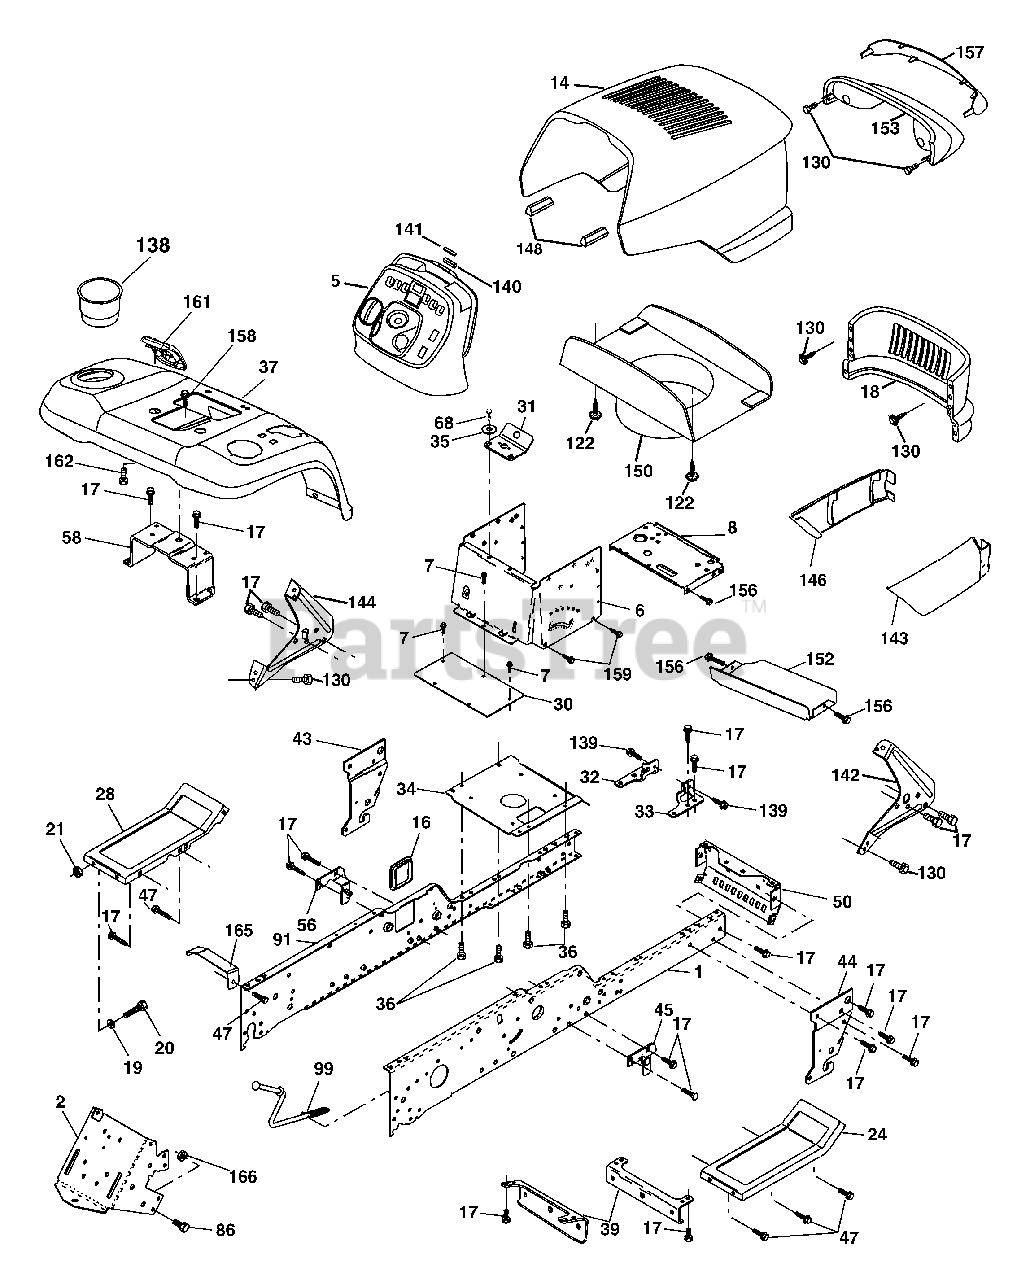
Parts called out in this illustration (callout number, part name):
1	Rail, Frame RH
2	Drawbar, Gt
5	Dash
6	Dash Asm., Lower
7	Screw, Thd Cut 1/4-20x 1/2
8	Support, Battery
14	Hood Asm., Pnt
16	Cover, Access
17	Screw, 3/8-16 x 3/4
18	Grille
19	Washer 13/32 x 13/16 x 12 Ga.
20	Bolt, Fin Hex 3/8-16 x 1
21	Nut, Lock Hex w/Ins. 3/8-16 Unc
24	Footrest, RH
28	Footrest, LH
30	Saddle, Hydro 1995
31	Bracket, Supt 1-pc VGT Steering
32	Bracket, Pivot Chassis LH
33	Bracket, Pivot Chassis RH
34	Plate Asm. Engine Chassis
35	Washer 11/32 x 11/16 x 16 Ga.
36	Screw 5/16-18 x 3/4
37	Fender, Pnt.
39	Bracket, Axle Front
43	Bracket, Spnsn Front Lh
44	Bracket, Spnsn Front Rh
45	Bracket Asm., Susp Chassis Rh
47	Screw Thdrol 3/8-16 x 1/2 TYT
50	Bracket, Chassis Front
56	Bracket Asm., Susp Chassis Lh
58	Bracket Asm., Fender
68	Screw, Thd 5/16-18 x 1/2
86	Bolt, Fin Hex 7/16-14 Unc x 1
91	Rail, Frame Lh
99	Rod By Pass
122	Screw Hex Wshd 8-18 x 7/8
130	Screw HWHD Hi-Lo #13-16 x 3/4
138	Cupholder YTGT
139	Bolt Shoulder 5/16-18 TT
140	Magnet YTGT
141	Stricker Plate YTGT
142	Bracket Dash RH
143	Skirt Grill RH
144	Bracket Dash LH
146	Skirt Grill LH
148	Extrusion Bumper
150	Duct Heat Hood
152	Shield Browning
153	Light Box Asm. w/Lens
156	Screw 5/16-18 x 3/4
157	Lens, Bar
158	Screw Thdrol 3/8-16 x 1/2
159	Screw 3/8-16 x 3/4
161	Console Fuel Window
162	Screw 1/4-1/2
165	Bracket Support Tank
166	Nut, Crownlock 7/16-14Unc
